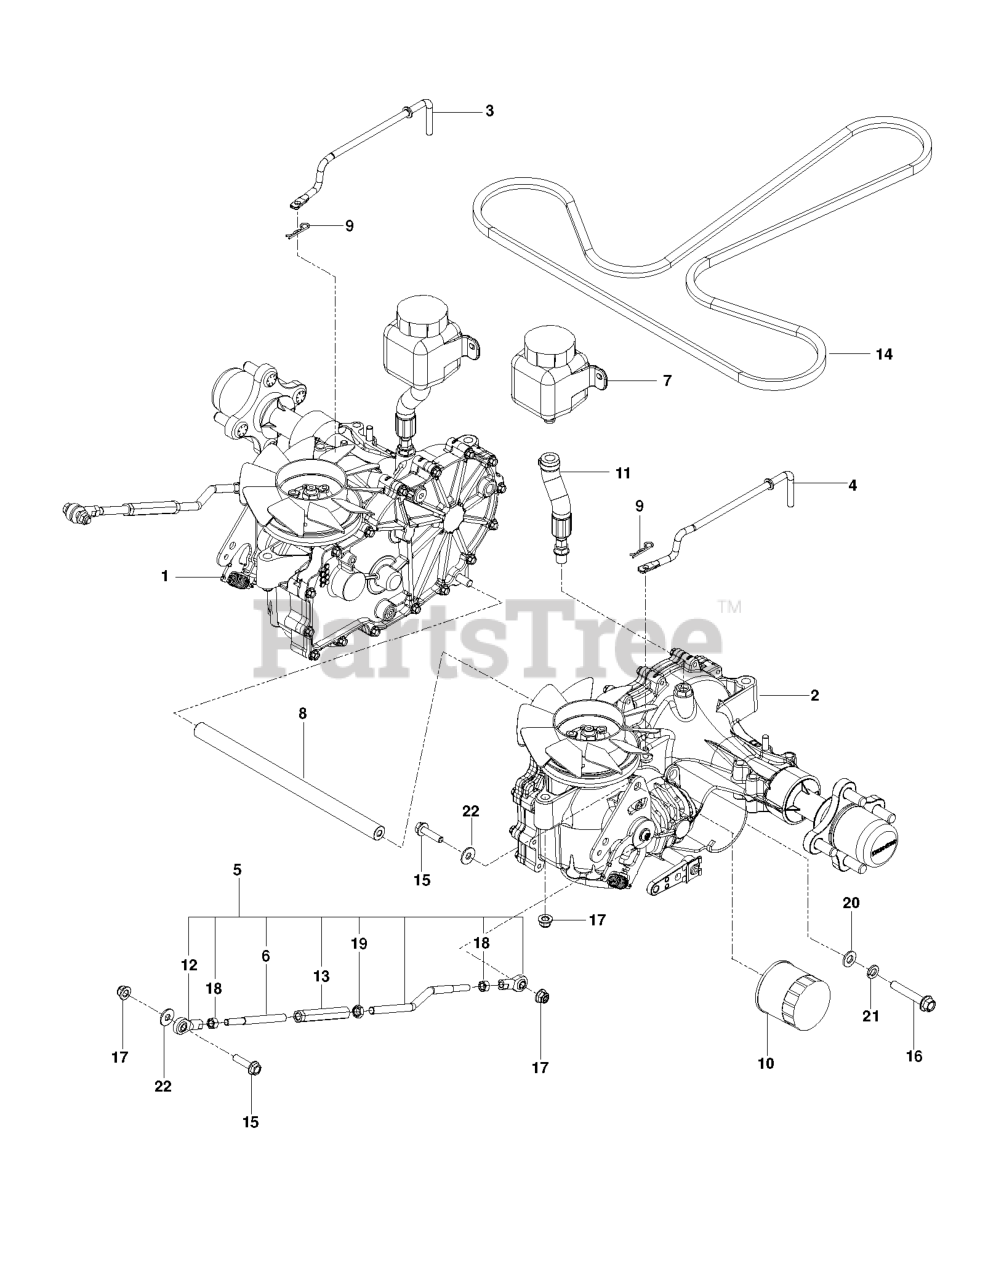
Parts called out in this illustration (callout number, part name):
1	HG_TRANS, ZT-3400, RT
2	HG_TRANS, ZT-3400, LT
3	LINKAGE, RIGHT BYPASS
4	LINKAGE, LEFT BYPASS
5	ASSEMBLY, CONTROL LINKAGE
6	LINKAGE, CONTROL, FT
7	TANK.EXPANSION.350ML 71328
8	SHAFT, TIE ROD
9	HAIRPIN #2
10	HG_FILTER, ZT4800 52114
11	ASSEMBLY, HOSE, EXPANSION
12	BALL JOINT, RIGHT HANDED
13	TURNBUCKLE, 3/8
14	BELT, "AX", 86.7"
15	HHFS 5/16-18 X 1.25 TPBLT GD 5
16	HCS 3/8-16X2-1/4 LOC PATCH GR8
17	5/16-18 NYLOC FLANGE NUT
19	NUT 3/8-24 JAM
20	WASHER 3/8 SAE FLAT
21	SLW 3/8 STD
22	WASHER 5/16 FLAT
